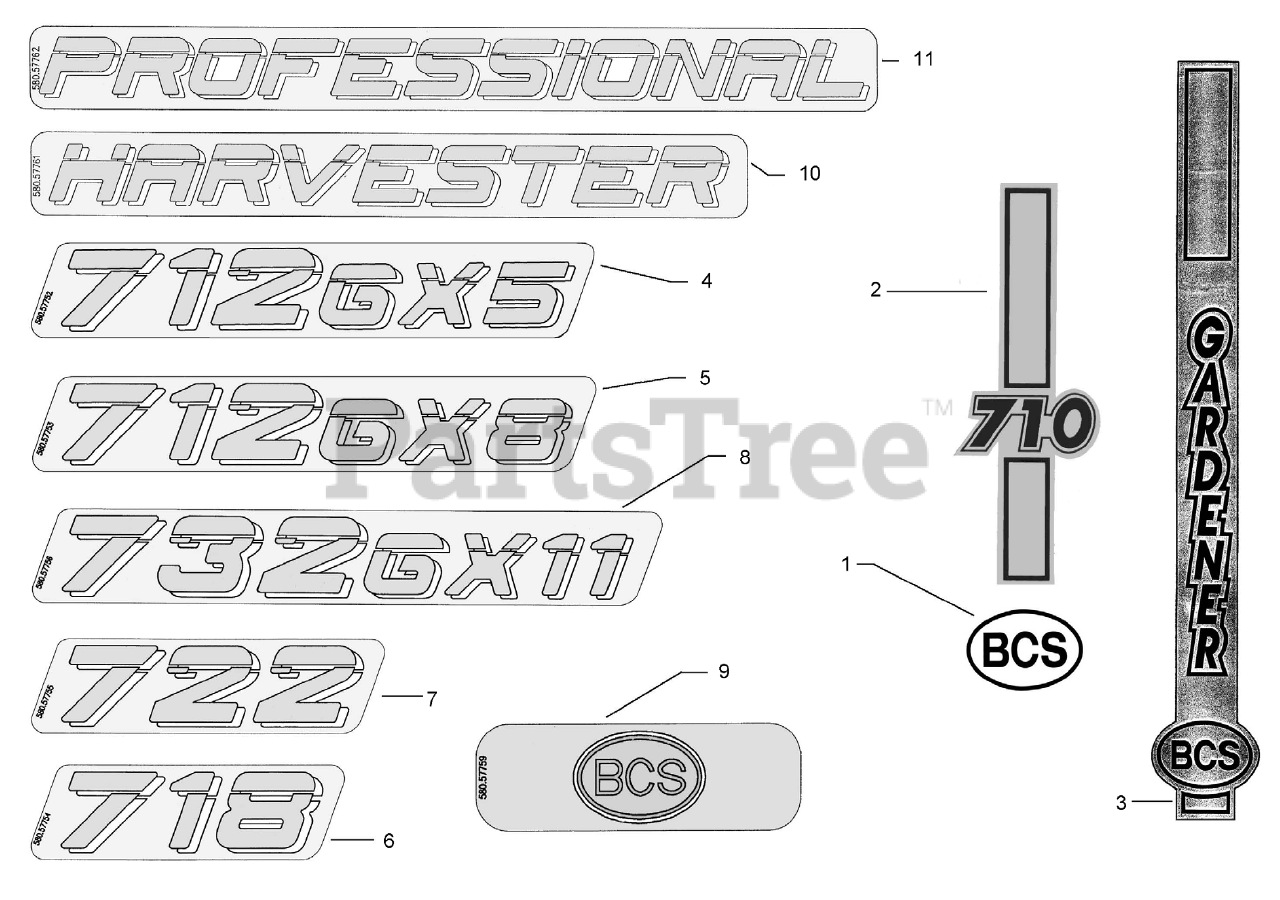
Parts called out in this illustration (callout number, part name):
1	DECAL, BCS LOGO
2	DECAL, 710
3	DECAL, GARDENER
4	DECAL, 712GX5
5	DECAL, 712GX8
6	DECAL, 718
7	DECAL, 722
8	DECAL, 732GX11
9	DECAL, BCS LOGO
10	DECAL, HARVESTER
11	DECAL, PROFESSIONAL
